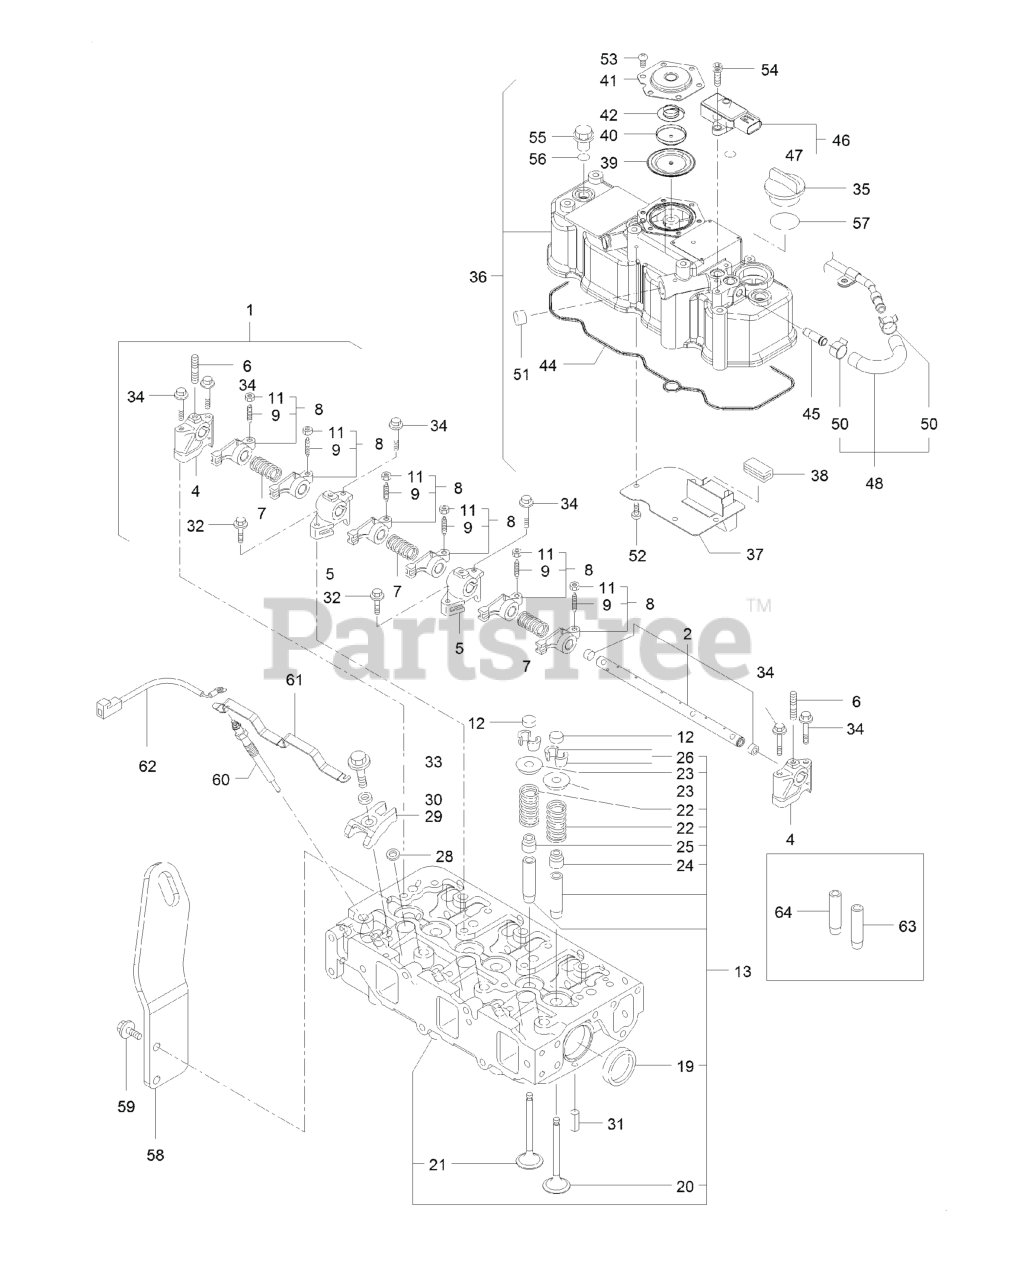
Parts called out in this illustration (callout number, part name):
1	SHAFT ASM
4	Support
5	Support
6	BOLT,STUD
8	Arm-Rocker
9	SCREW-ADJUST, VALVE
12	Cap-Valve
13	CYLINDER HEAD ASM
23	Retainer-Spring
24	SEAL-STEM, VALVE
25	SEAL-STEM, VALVE
26	PIN-COTTER
28	GASKET-INJECTOR
29	Retainer-Injector
30	WASHER-INJECTOR
31	PIN-SPRING
35	COVER-FILLER
36	CYLINDER HEAD COVER ASM
39	DIAPHRAGM
41	PLATE-BREATHER
42	SPRING-DIAPHRAGM
44	GASKET-HEAD, CYLINDER
46	SENSOR-PRESSURE
47	O RING-SENSOR, PRESSURE
48	HOSE ASM
50	Clip-Hose
58	LIFTER-ENGINE
59	BOLT
60	PLUG-GLOW
61	CONNECTOR-PLUG, GLOW
62	HARNESS-WIRE
64	GUIDE-VALVE
